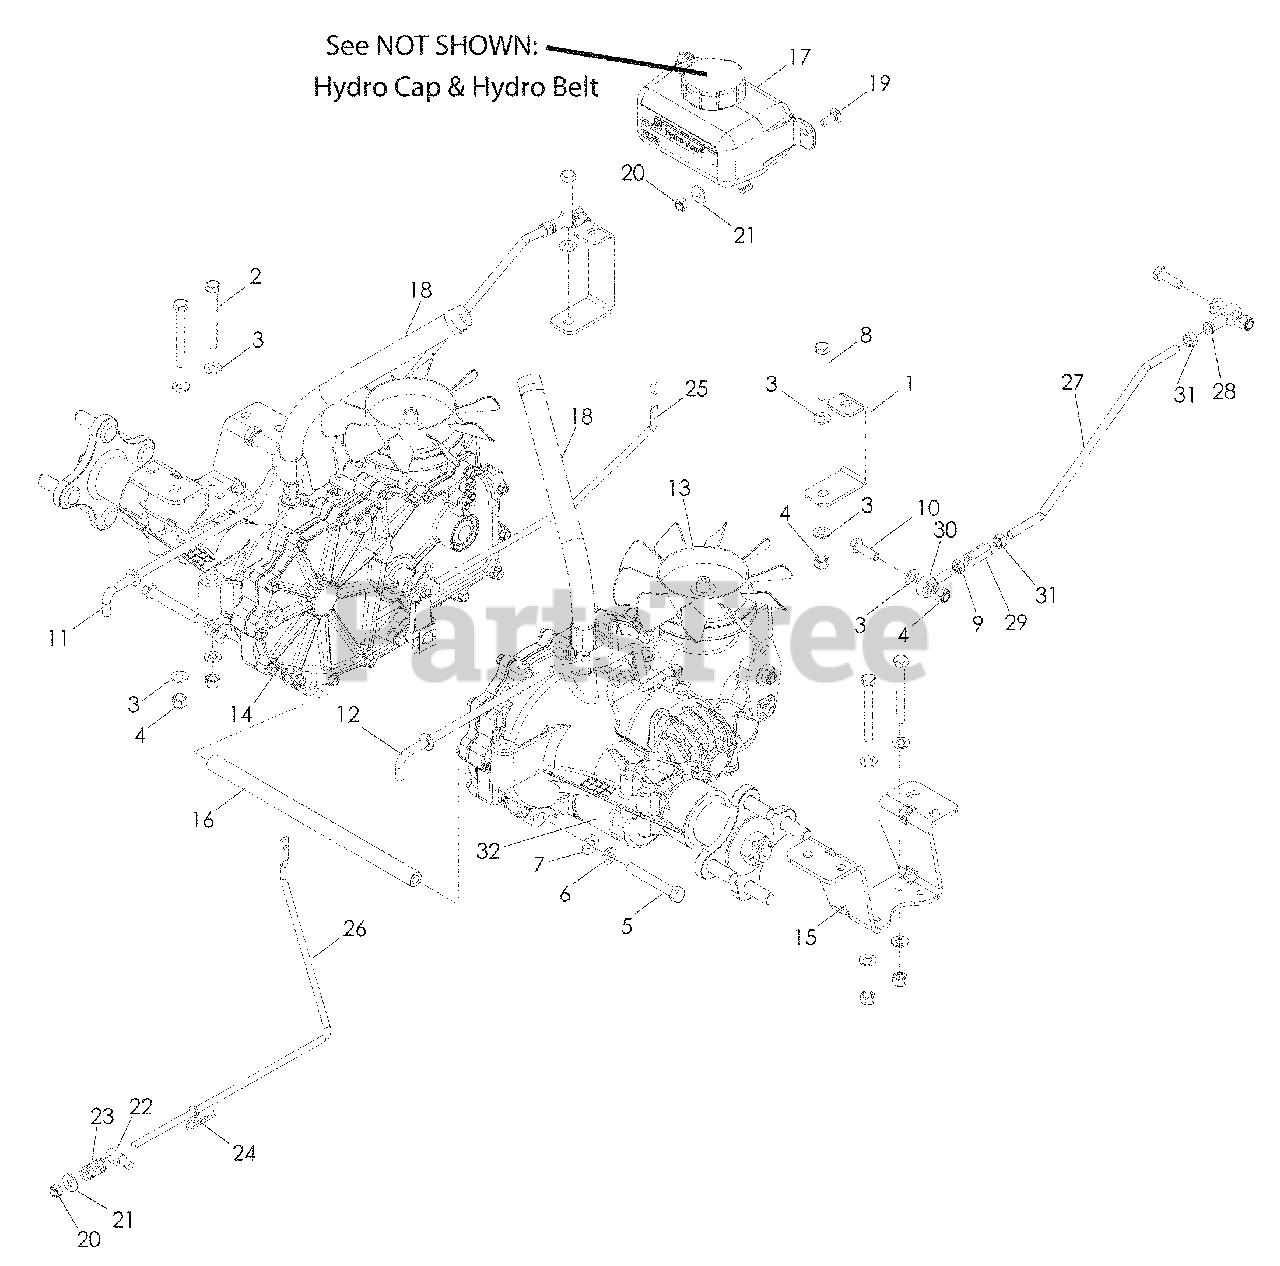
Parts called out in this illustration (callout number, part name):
1	SUPPORT, TRANSMISSION
2	HCS 5/16-18 x 2¾
3	WASHER 5/16 SAE FLAT
4	NUT 5/16-18 HEX NYLOC
5	HCS 3/8-16 x 2½
6	WASHER, 3/8 SLW
7	WASHER 3/8 SAE FLAT
8	HCS 5/16-18 x 2¼
9	NUT 5/16-24 HEX JAM LH
10	HCS 5/16-18 x 1
11	LINK ARM, BYPASS, RT
12	LINK ARM, BYPASS, LT
13	TRANS, ZT-2800 RT
14	TRANS, ZT-2800 LT
15	EZT MOUNT, REAR
16	SPACER TUBE, EZT
17	EXPANSION TANK w/CAP
19	RHSNB ¼-20 x ¾ GR2
20	NUT ¼-20 HEX NYLOC
21	WASHER ¼ FLAT
22	BRAKE SWIVEL
24	HAIRPIN COTTER
25	ROD, EZT BRAKE LT
26	ROD, EZT BRAKE RT
27	ROD, MOTION CONTROL
28	ROD END RH
29	COUPLER, ROD END
30	ROD END MALE LH
31	NUT 5/16-24 HEX
